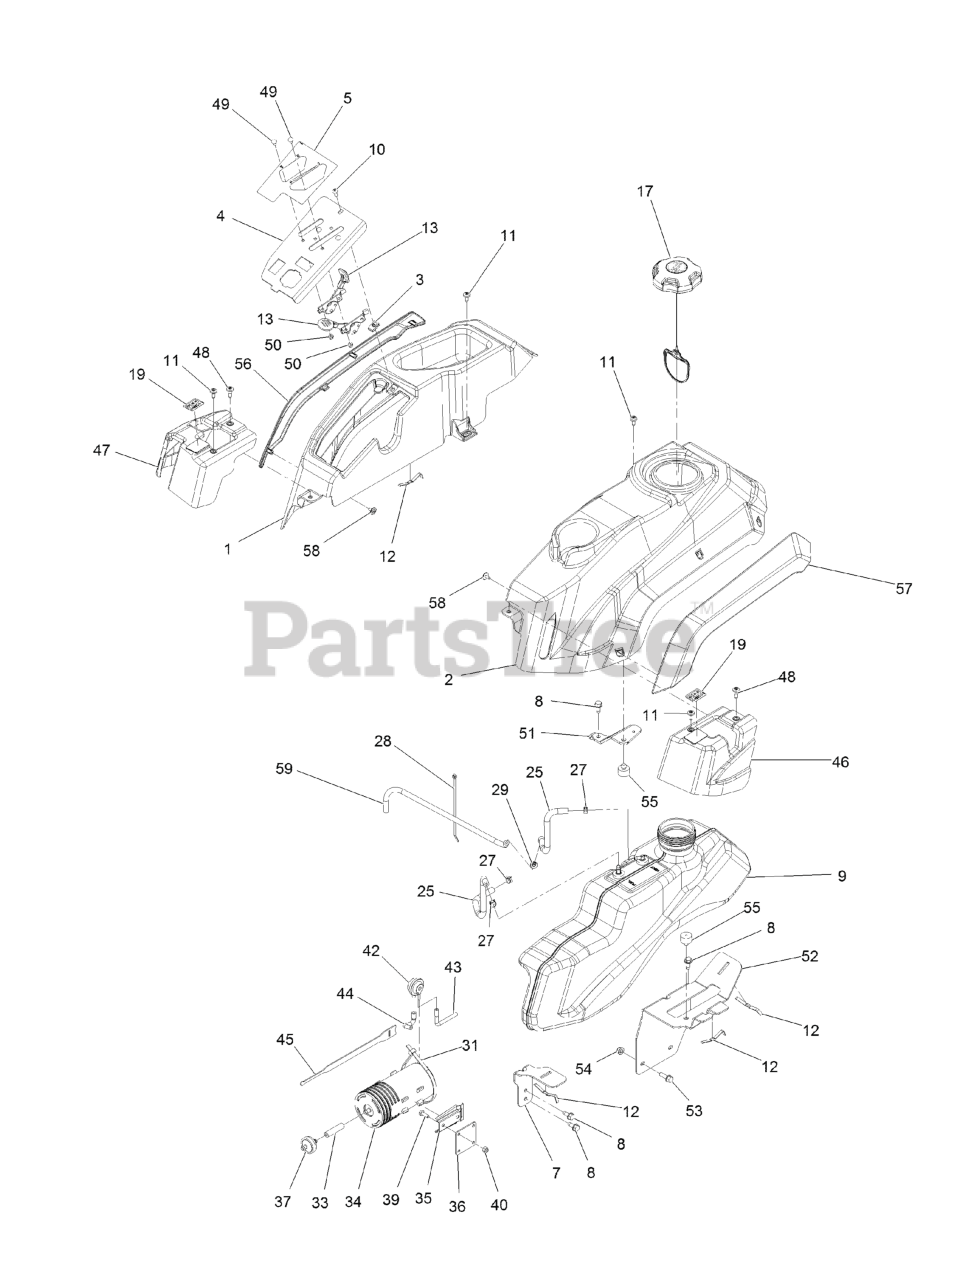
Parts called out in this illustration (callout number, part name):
1	POD-RH, NARROW
2	POD-LH, NARROW
4	PANEL-CONTROL, NARROW
5	DECAL-CONTROL
7	SUPPORT-TANK
8	Screw-HWH 5/16-18 X 3/4 Tf
9	TANK, FUEL
10	SCREW-PRH
11	SCREW-SHOULDER
12	SPRING
13	CABLE-CONTROL, THROTTLE
13	CABLE-CONTROL, CHOKE
17	CAP-FUEL, RATCHETING
19	DECAL-MOTION CONTROL
25	HOSE-FUEL
27	CLAMP-HOSE
28	TIE-CABLE
29	ADAPTOR-ORIFICE
31	TIE-CABLE
33	HOSE-FUEL
34	CANISTER-CARBON, 800CC
35	BRACKET-CANISTER, CARBON
36	PLATE-ADAPTER
37	FILTER-FUEL, INLINE
39	SCREW-HH
40	NUT-LOCK, NI
42	VALVE-CONTROL, VACUUM
43	HOSE-VENT, FORMED
44	HOSE-VENT, FORMED
45	STRAP-VELCRO, CABLE TIE
46	Cover, Motion Control LH
47	Cover, Motion Control RH
48	SCREW-SHOULDER
49	BOLT-CARR
50	NUT-LOCK, NI
51	BRACKET-CLAMP
52	BRACKET-SUPPORT TANK
53	SCREW-HHF
54	NUT-HF, NI
55	BUMPER-GROMMET
56	FENDER-RH
57	FENDER-LH
58	SCREW-TORX
59	HOSE-FUEL
